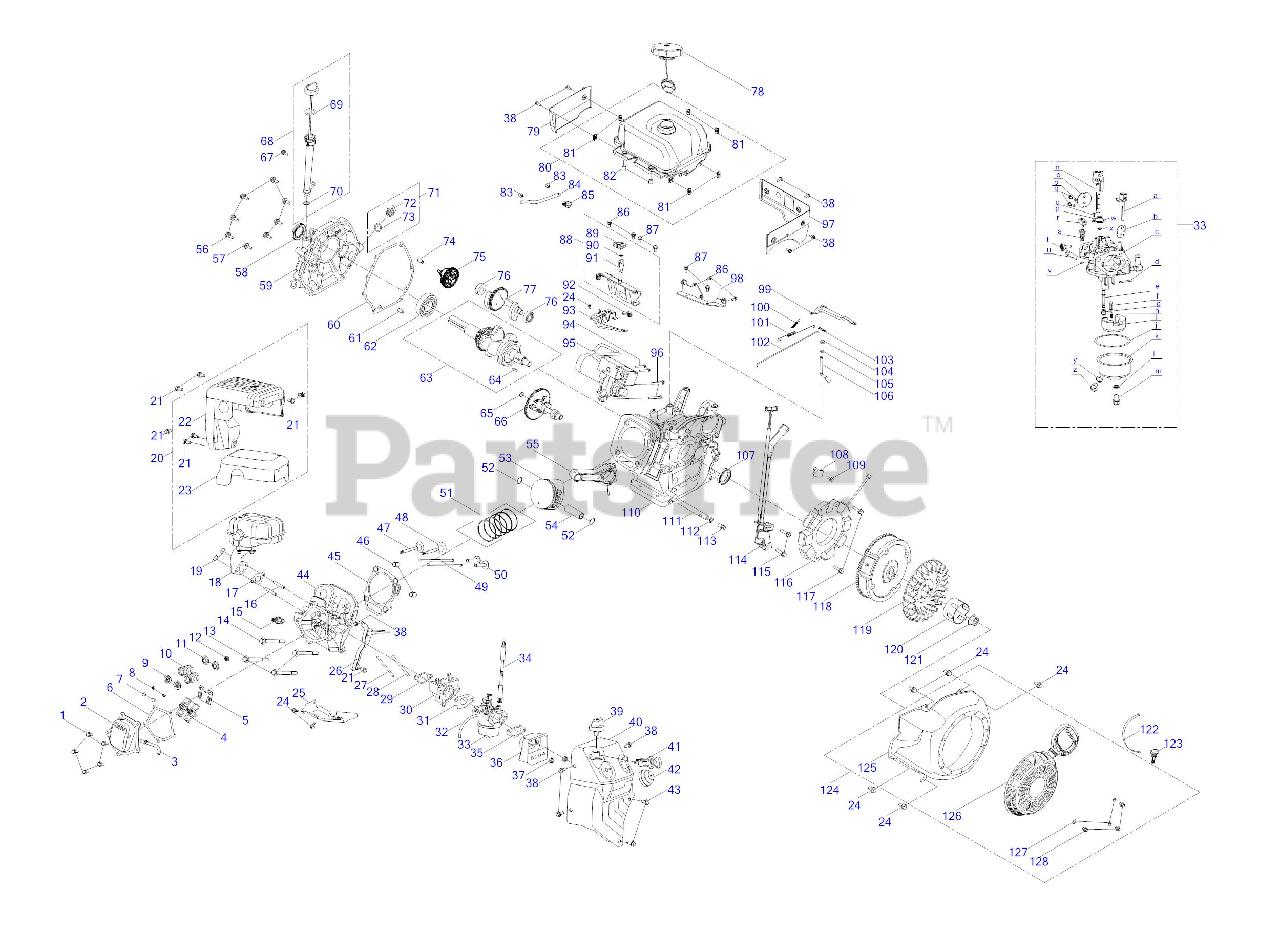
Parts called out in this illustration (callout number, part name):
1	Bolt, M6X16
2	Valve Cover
3	Breather Hose
4	Rocker Arm Assembly
5	Rocker Arm Base
6	Gasket, Valve Cover
7	Valve Adjust Cap, Exhaust
8	Valve Locker
9	Valve Spring Seat
10	Valve Spring
11	Valve Spring Seat
12	Intake Valve Seal
13	Bolt, M10X1.25X87
14	Bolt, M10X1.25X65
15	Spark Plug
16	Stud, M8X48.5
17	Gasket, Muffler
18	Muffler
20	Muffler Guard
21	Bolt, M6X10
22	Muffler Shroud
23	Muffler Inner Shield
24	Bolt, M6X12
26	Snow Guard
27	Stud, M6-8X108
28	Stud, M6-8X126
29	Gasket, Carburetor Insulator
30	Insulator
31	Carburetor Gasket
32	Fuel Hose, 3.2X6.5X170
33	Carburetor
34	Choke Linkage
35	Gasket, Air Filter
36	Heater Box
38	Bolt, M6X14
39	Choke Lever
40	Control Panel
41	Stop Switch
43	Bolt, M6X20
44	Cylinder Head
45	Gasket, Cylinder Head
46	Pin, 12X20
47	Exhaust Valve
48	Intake Vavle
49	Push Rod
50	Tappet
51	Piston Ring Set
52	Circlip
54	Piston Pin
55	Connecting Rod Assembly
56	Bolt, M8X38
57	Bolt, M8X45
58	Oil Seal, 35X52X7
59	Crankcase Cover
60	Gasket, Crankcase
62	Bearing, 6207
63	Crankshaft
64	Woodruff Key
65	Washer, 16.2X0.3X24
66	Camshaft
67	Bolt, M6X18
68	Dipstick
69	O-Ring, 21X2.77
70	O-Ring, 13.5X2.5
71	Oil Plug
72	Oil Plug
73	O-Ring, 16X3
74	Pin, 7X14
75	Governor Gear
76	Bearing, 6202
77	Balance Shaft
79	Decorative Sheet, Right
81	Fuel Tank Mount Thread Tab
82	Bush, 10X14X14
83	Clamp
84	Fuel Hose, 6.3X12.5X255
85	Clip
86	Bolt, M8X28
87	Bolt, M8X14
88	Front Bracket, Fuel Tank
89	Rubber Grommet
90	Retaining Ring, 10
91	Front Bracket, Fuel Tank
92	Throttle Lever Knob
93	Governor Gear Bracket Assembly
94	Screw, M4X48
95	Electric Starter
96	Bolt, M8X55
97	Decorative Sheet, Left
98	Fuel Tank Base
99	Governor Lever
100	Governor Spring
101	Idle Spring
102	Throttle Linkage
103	Cotter Pin
104	Oil Seal, 8X14X4
105	Washer, 8X0.8X20
106	Governor Gear Shaft
107	Oil Seal, 35X52X7
108	Wire Board
109	Bolt, M6X8
111	Oil Drain Pipe
112	Washer, 10X1.5X16
113	Earth Bolt
114	Ignition Module
115	Bolt, M6X28
116	Charging Coil
117	Bolt, M6X30
119	Cooling Fan
120	Starter Cup
121	Nut, M16X1.5
122	Tape, L=150mm
123	Stop Switch Key
124	Recoil Starter
125	Blower Housing
126	Recoil Starter
127	Washer, 6
128	Bolt, M6X10
